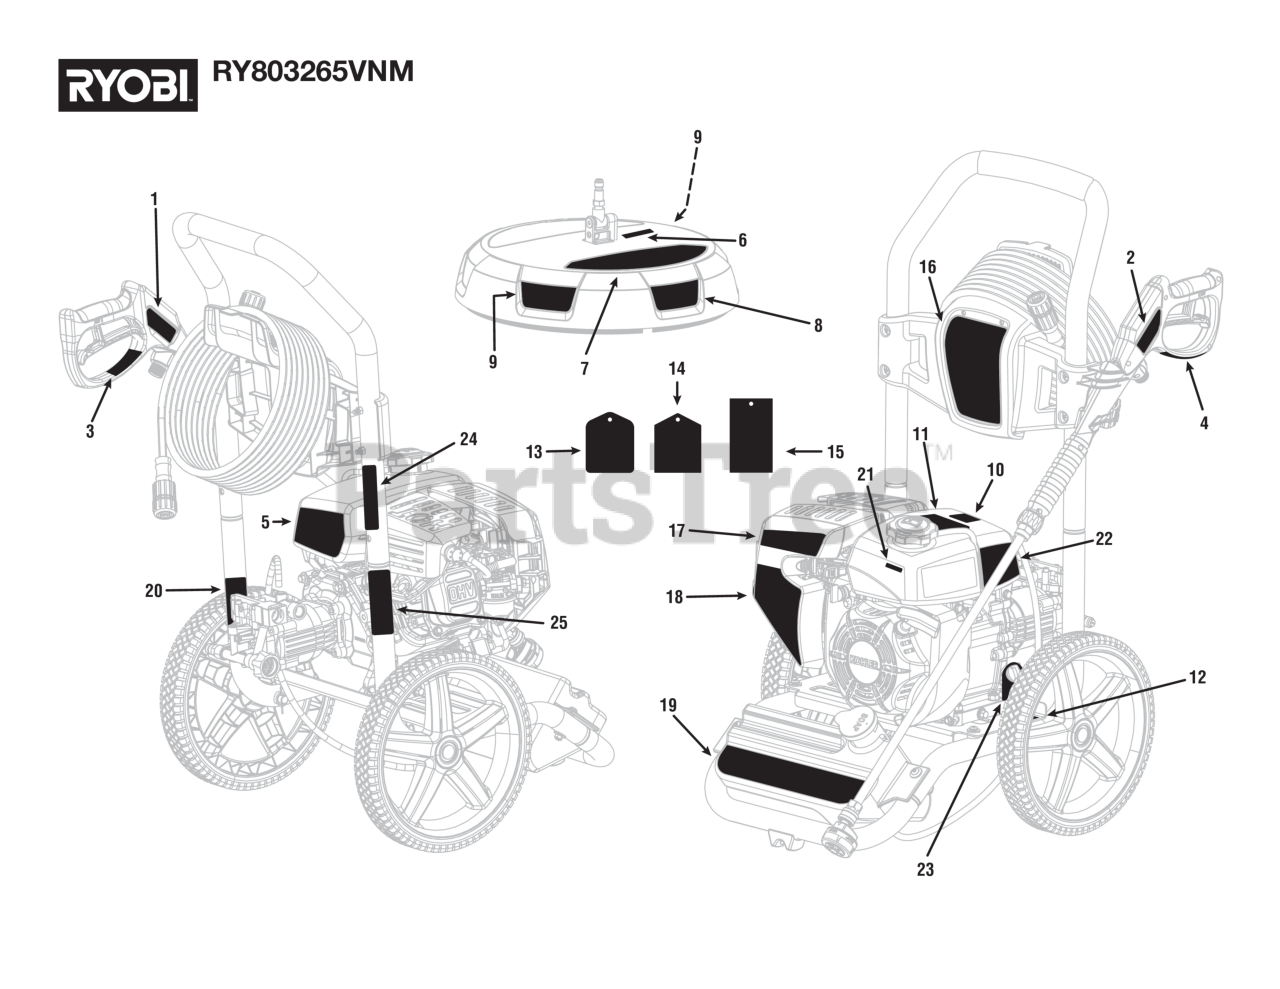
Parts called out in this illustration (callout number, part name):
1	LABEL, TRIGGER HANDLE LOGO
2	Trigger Handle Warning Label (English)
3	Label (Trigger Handle Warning, French & Spanish)
4	Trigger Handle Data Label
5	Danger Label
6	Power Control Label
7	Surface Cleaner Performance Label
8	Callout Label
9	Cut Foot Icon Label
10	Hot Surface and
11	No E85 Label
12	Oil Fill Location Label
13	Quick Start Hangtag
14	5- In- 1 Nozzle Hangtag
15	Danger Hangtag
16	Performance Label
17	Choke Label
18	Cover Label
19	Detergent Tank Label
20	Warning Label
21	EMC ICES-2/NMB-2 Label (Canada)
22	Danger Label
23	Label (Oil Dipstick Hangtag)
24	Inquires Label (Ryobi)
25	UL Fire Warning Label Spark Arrestor)
